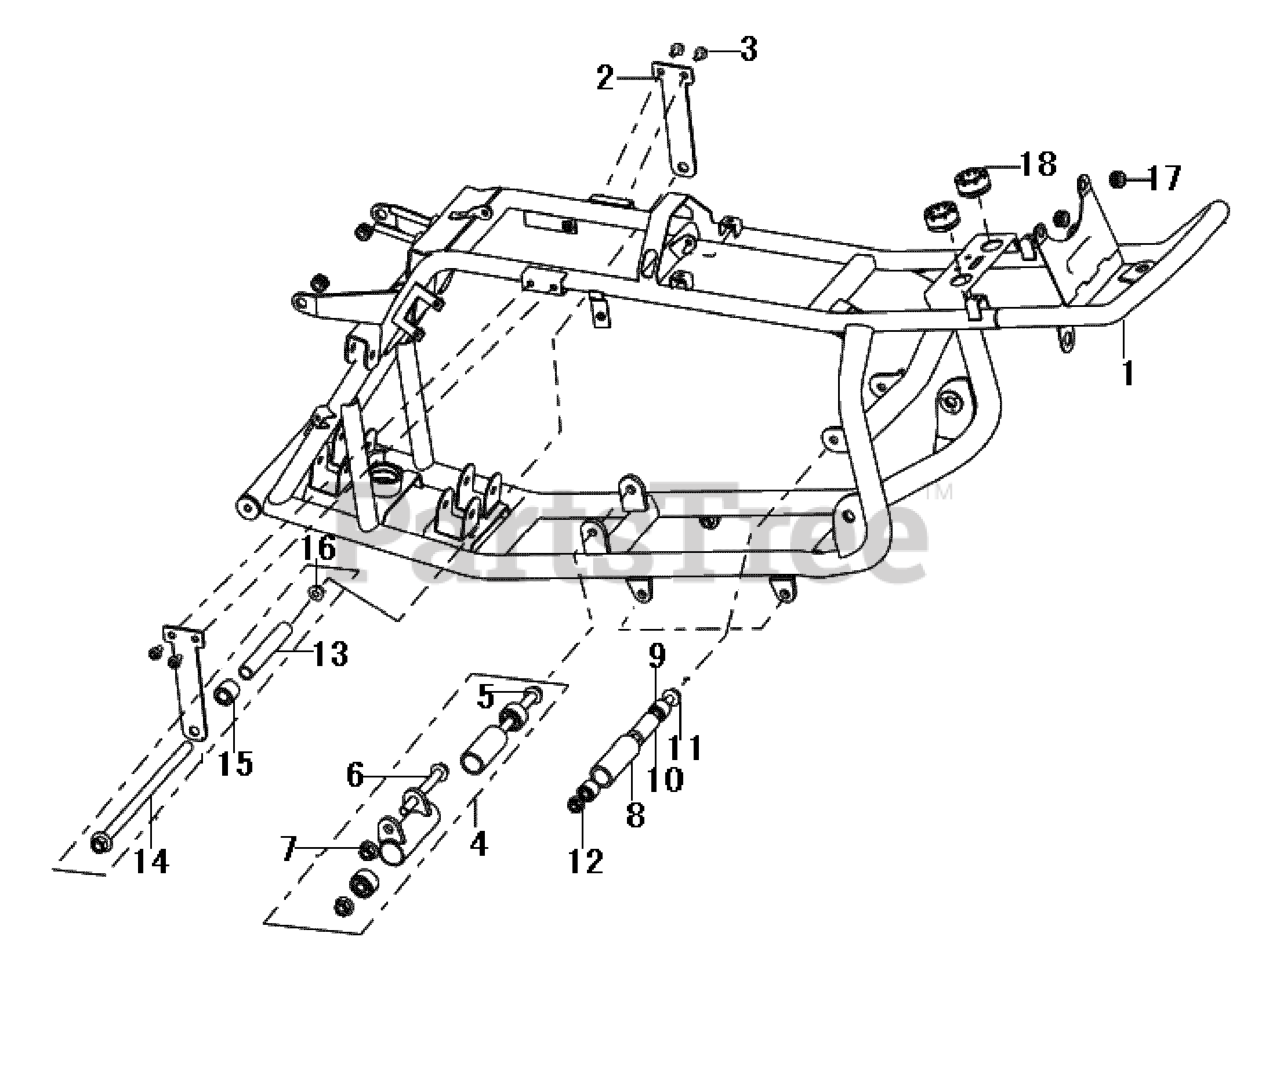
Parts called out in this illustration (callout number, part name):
1	FRAME ASSY.
2	BRACKET, SUPPORT
4	ENGINE MOUNT ASSY.
9	BUSHING
18	ABSORBER, RUBBER
